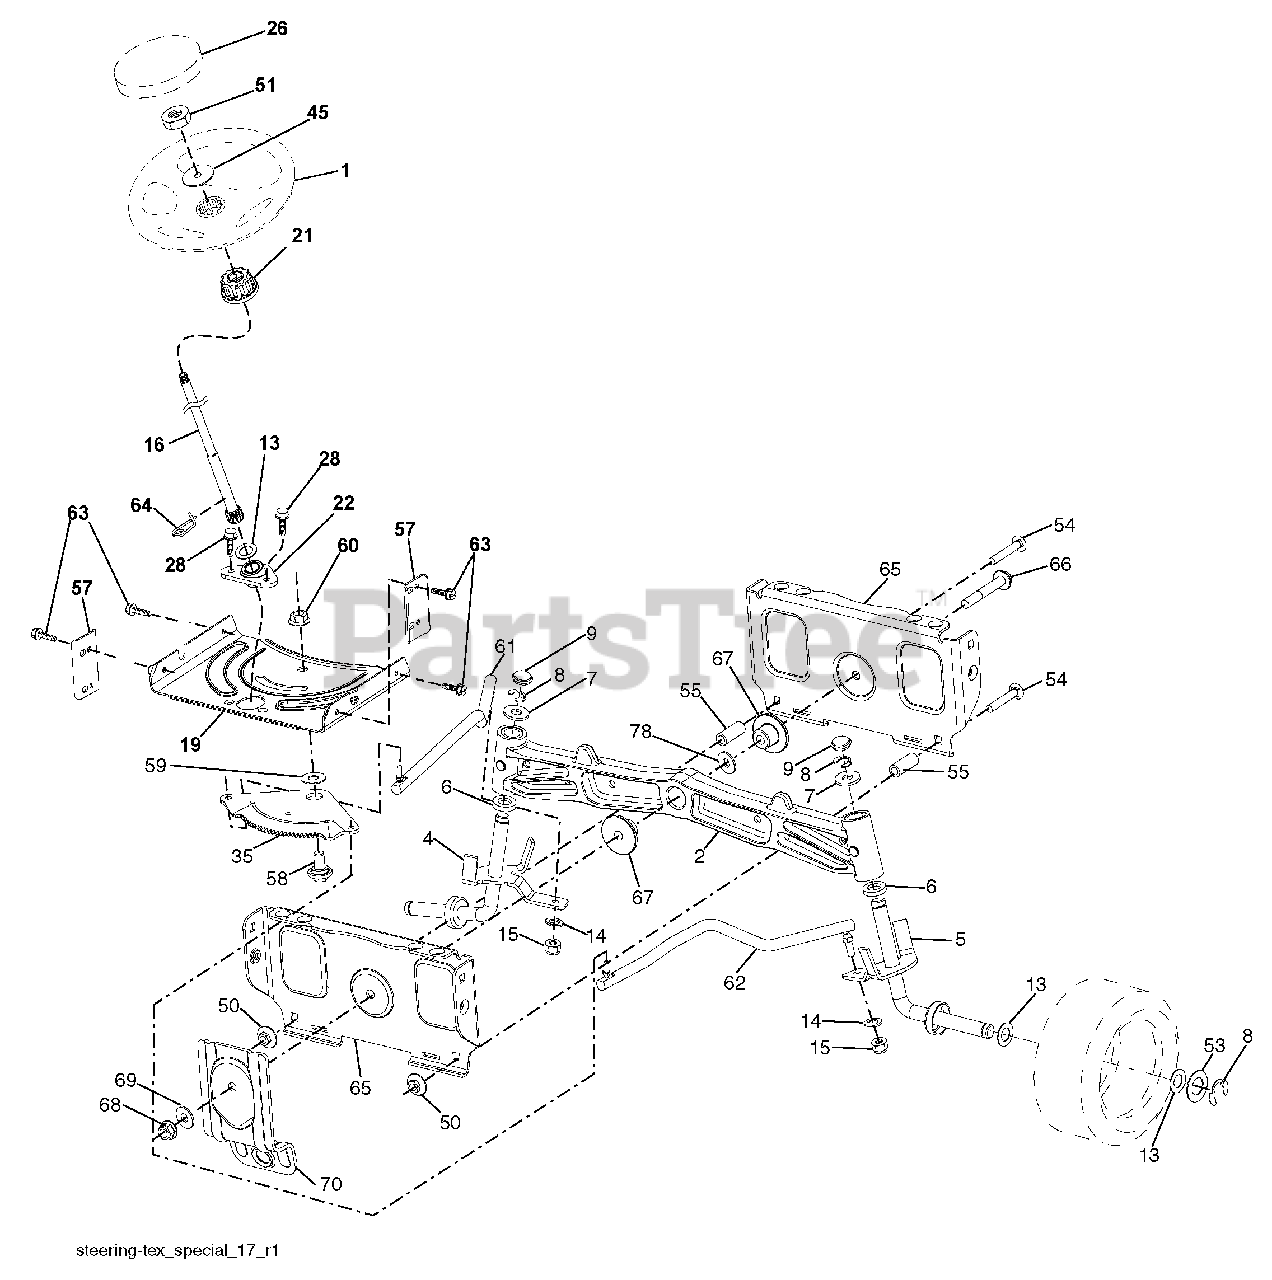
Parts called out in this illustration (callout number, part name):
1	Wheel, Steering
2	Axle Asm., Front
4	Spindle Asm., LH
5	Spindle Asm., RH
6	Bearing, Race Thrust Harden
7	Washer 25/32 x 1-5/8 x 16 Ga.
8	Ring, Clip #T5304-75
9	Cap, Spindle
13	Washer 25/32 x 1-1/4 x 16 Ga.
14	Washer, Lock Hvy Hlcl Spr 3/8
15	Nut, Crown Lock 3/8-24 unf
16	Shaft Steering
19	Plate Steering
21	Adapter, Wheel Steering
22	Steering Support Lower
26	Insert, Wheel Steering
28	Screw 3/8-16 x 3/4
35	Gear, Sector Plate
45	Washer 9/16 ID x 2-3/8 OD 12 Ga.
50	Nut Lock Flg. 3/8-16 unc
51	Nut Hex Jam Toplock 1/2-20 unf
53	Washer Hardened .793 x 1.637 x .060
54	Bolt Hex 3/8-16 unc x 2-1/4
55	Spacer Brace Axle
57	Bracket Upstop
58	Bolt Shoulder Sector Pivot CFM
59	Washer Thrust Sector Steering
60	Nut Flange Lock 5/8-11
61	Draglink, LH
62	Draglink, RH
63	Screw 5/16-18 x 3/4
64	Retainer Clip Spring Steering
65	Brace Axle Front
66	Bolt Hex Fghd 7/16-14 x 3 Serr
67	Bushing PM Front Axle
68	Nut Lock Flange 7/16-14 Gr. 5
69	Washer 1.5 x .505 x .118
70	Bracket Deck Susp. Front
78	Washer Thrust
